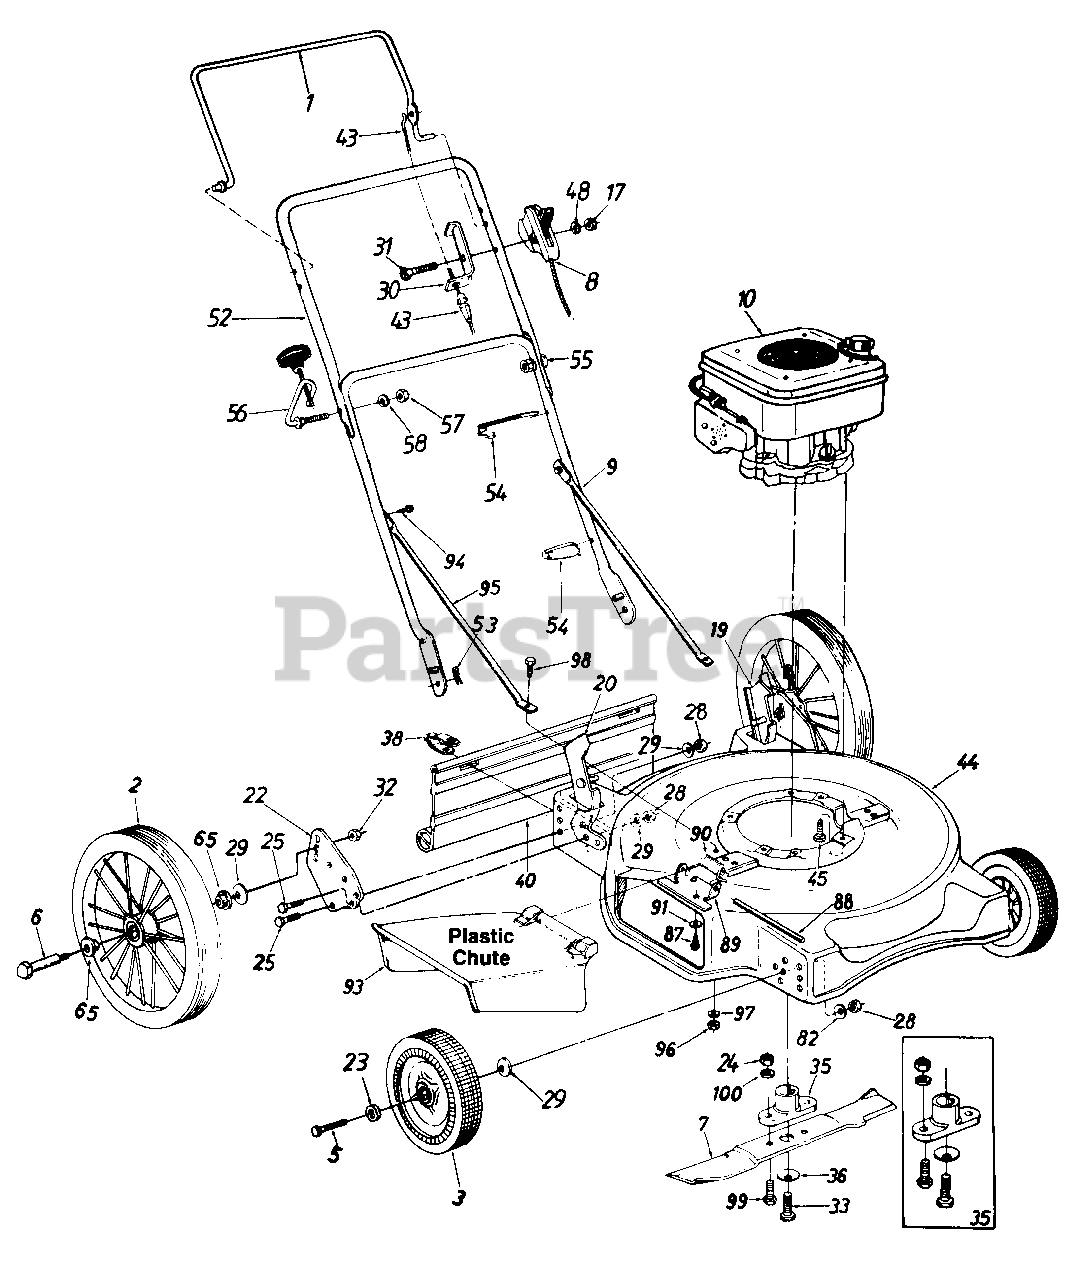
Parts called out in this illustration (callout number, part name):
1	Control Handle Ass'y.
2	Rear Wheel Ass'y. Comp.
3	Front Wheel Ass'y. Comp.
5	Front Axle Bolt
6	Rear Axle Bolt
7	22" Blade
8	Throttle Control Ass'y. Comp.- 36"
9	Lower Handle
10	3.5 H.P. Engine-See Breakdown
17	Hex Nut 1/4-20 Thd.
19	Handle Mount Brkt.-L.H.
20	Handle Mount Brkt.-R.H.
22	Mounting Plate
23	Wave Wash. .53" I.D.
24	Hex Nut 3/8-24 Thd.
25	Hex Bolt 3/8-16 x .75" Lg.
28	Hex Nut 3/8-16 Thd.
29	Bell-Wash. .400" I.D. x .88"
30	Cable Brkt.
31	Hex Bolt 1/4-20 x 2.0" Lg.
32	Hex Cent. L-Nut 3/8-16 Thd.
33	Hex Bolt 7/16-20 x 1.5" Lg. (Grade 5)
35	Blade Adapter Kit
36	Bell-Wash...46" I.D.
38	Hinge Clip
40	Rear Flap Ass'y.
43	Control Cable-43"
44	22" Deck Ass'y.
45	Hex Wash. Hd. TT-Tap Scr. 3/8-16 x 1.00" Lg.
48	Spr. Wash. .265" I.D.
52	Upper Handle
53	Intern. Cot. Pin 5/16" Dia.
54	Cable Tie
55	Curved Carriage Bolt 5/16-18 x 1.38" Lg.
56	Rope Guide Bolt
57	Hex Nut 5/16-18 Thd.
58	L-Wash. 5/16 I.D.*
65	Bearing 1/2" I.D.
82	Bell-Wash. .39" I.D. x 1.38"
87	Hex Wash. Hd. Tap Scr. 1/4-20 x .5" Lg.
88	Hinge Pin
89	Adapter Plate
90	Torsion Spring
91	Bell-Wash. .265" I.D. x .75" O.D.
93	Chute Deflector Ass'y. Comp.
94	Hex Wash. AB-Tap Scr. 5/16 x .75" Lg.
95	Strut Bar
96	Hex Nut 1/4-20 Thd.
97	Bell-Wash. 1/4" I.D.
98	Hex Bolt 1/4-20 x .62" Lg.
99	Hex Bolt 3/8-24 x 1" Lg.
100	L-Wash. 3/8" I.D.
